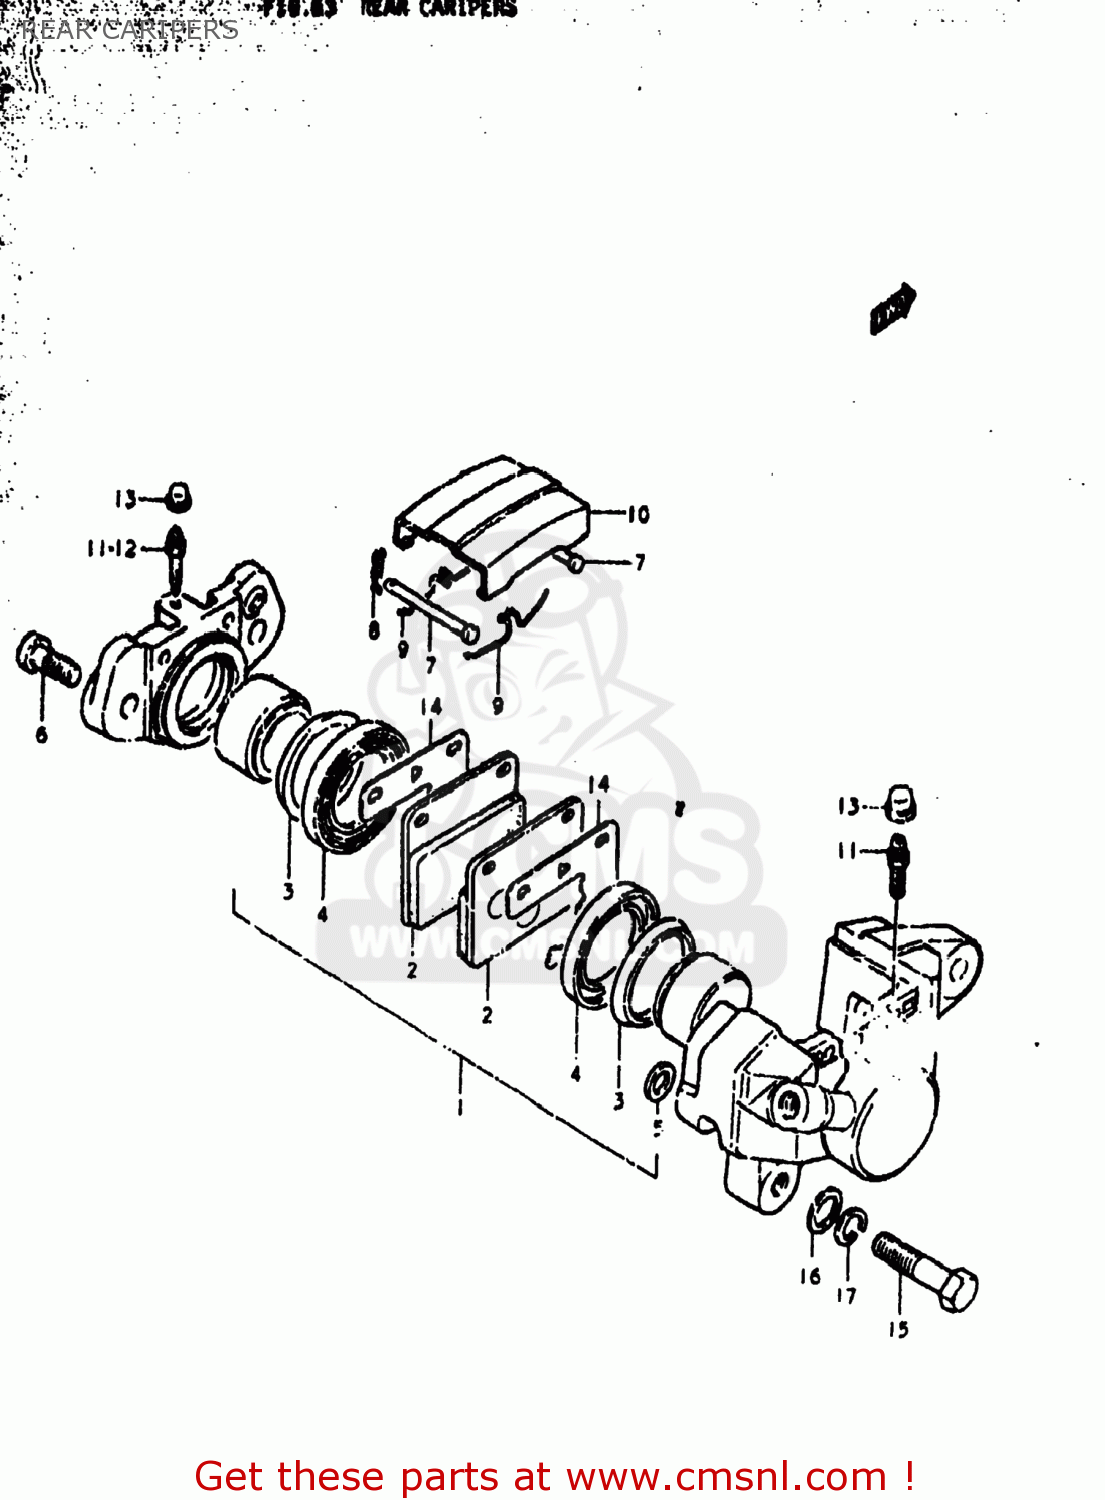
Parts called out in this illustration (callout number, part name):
1	PISTON SET
2	PAD,BRAKE
3	SEAL,PISTON
4	BOOT,PISTON
5	SEAL,PISTON
6	BOLT,HOUSING
7	PIN,PAD
8	CLIP,PAD PIN
9	SPRING
10	COVER,DUST
11	BLEEDER
12	BREATHER
13	CAP,BREATHER
14	SHIM,RR CALIPER
15	BOLT 10X34
16	WASHER
17	LOCK WASHER
